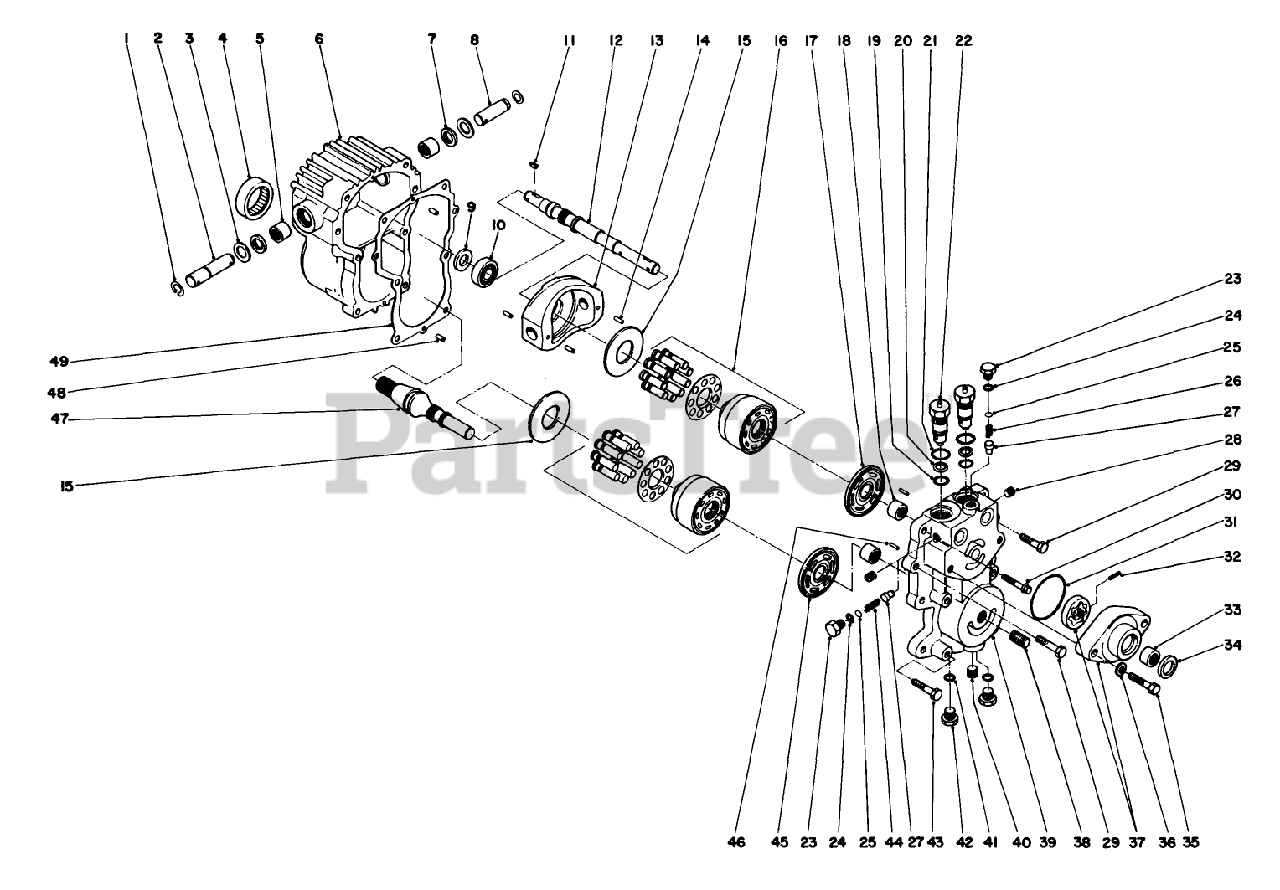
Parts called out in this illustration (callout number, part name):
1	RING-RETAINING
2	SHAFT-TRUNNION
3	WASHER-FLAT
4	BEARING-ROLLER
7	SEAL-LIP
8	SHAFT-TRUNNION
11	KEY-WOODRUFF
12	SHAFT-PUMP
14	PIN-SPRING
15	PLATE-THRUST
16	CYLINDER BLOCK KIT
17	PLATE-VALVE, PUMP
18	BEARING-NEEDLE
19	O-RING
20	RING-BACK UP
21	O-RING
22	CHECK VALVE KIT
23	PLUG-HH
24	O-RING
25	PACK-SHIM
26	SPRING
28	PLUG-PIPE
29	SCREW-HH
30	CAPSCREW
31	O-RING
33	BEARING
34	SEAL-LIP
36	WASHER
38	UNION-FILTER
40	Plug-Pipe
41	O Ring
42	PLUG-THREADED
43	SCREW-HH
44	SPRING-VALVE
45	PLATE-VALVE, MOTOR
46	PIN-DOWEL
47	SHAFT-MOTOR
49	GASKET
